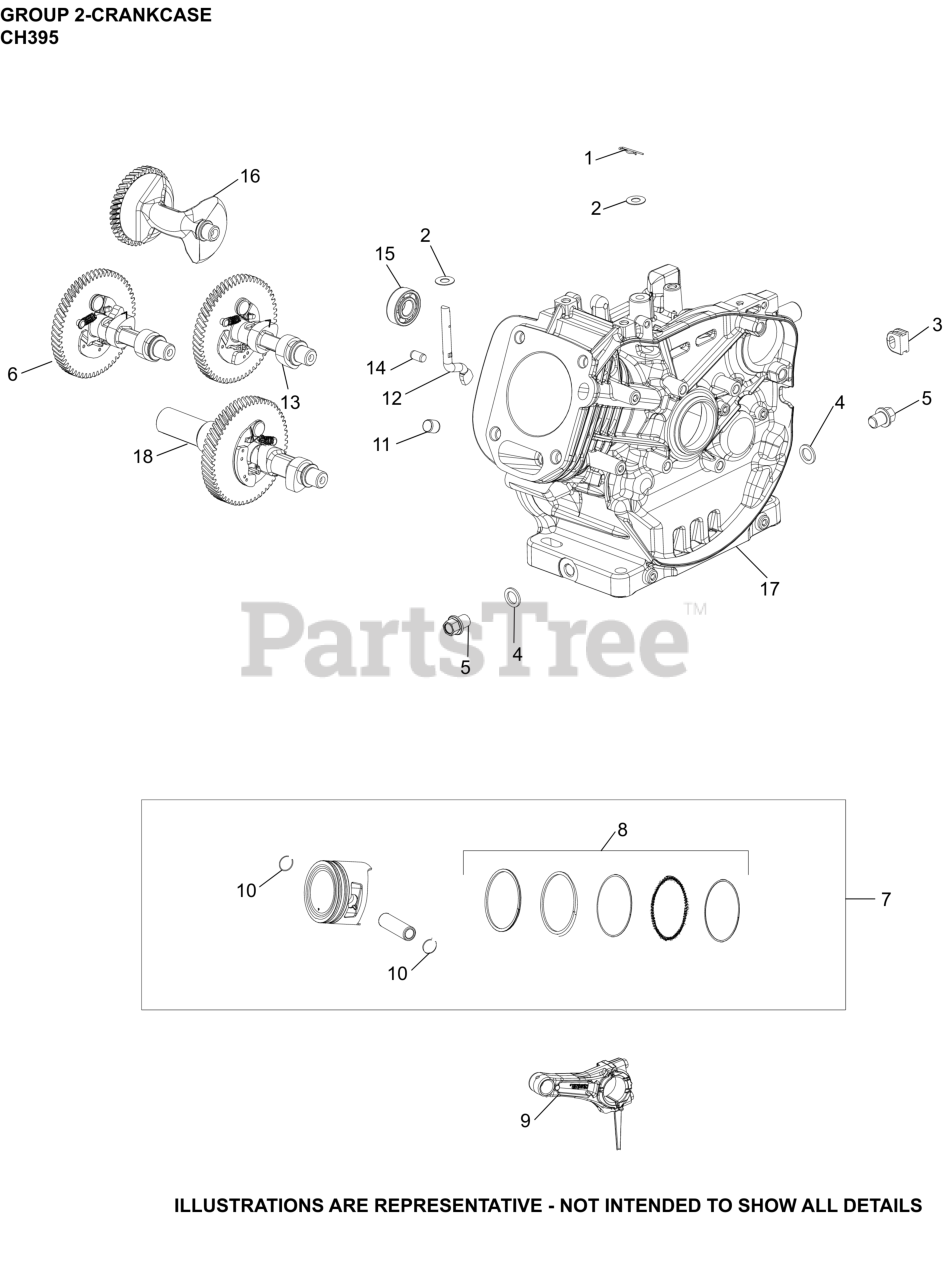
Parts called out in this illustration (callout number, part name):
1	CLIP, GOVERNOR SHAFT
2	WASHER, FLAT
3	GROMMET, CRANKCASE
4	WASHER, DRAIN PLUG
5	KIT, DRAIN PLUG
6	SEAL, RADIAL SHAFT
7	KIT, PISTON-USE 17 874 14-S
7	KIT, PISTON AND RINGS
8	RING SET- USE 17 874 06-S
8	RING, SET PISTION (std)
9	ROD, CONNECTING ASSEMBLY
10	RETAINER, PISTON PIN
11	PIN, DOWEL CYLINDER HEAD
12	SHAFT, GOVERNOR CROSS
13	CAMSHAFT ASSEMBLY
14	PIN, DOWEL
16	SHAFT, BALANCE
17	CRANKCASE
